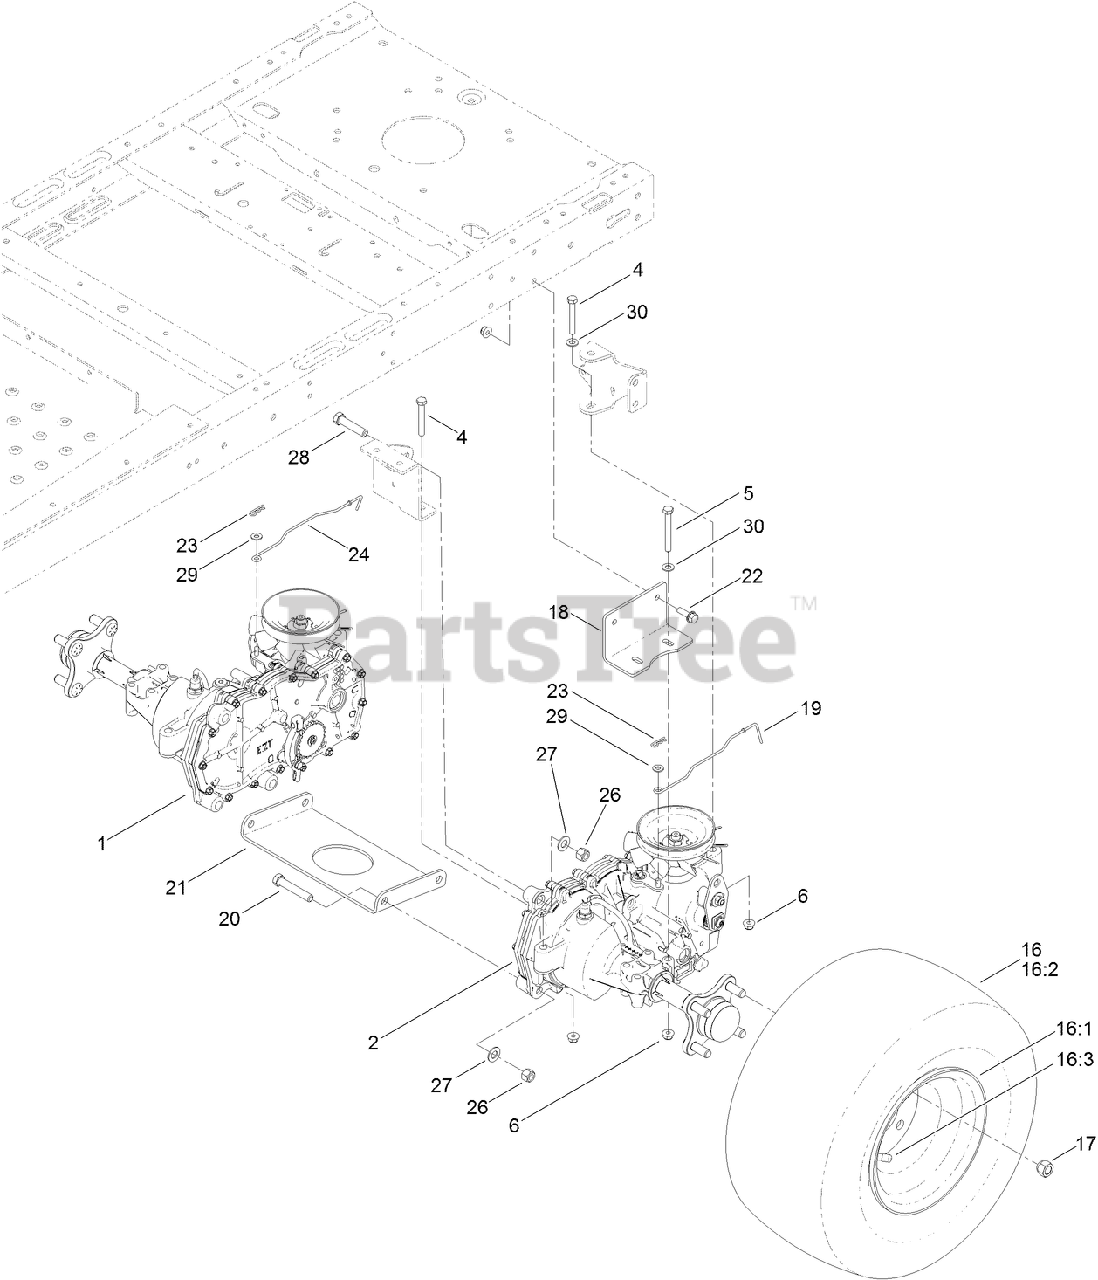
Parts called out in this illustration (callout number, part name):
1	RH HYDRO TRANSAXLE ASM
2	LH HYDRO TRANSAXLE ASM
4	SCREW-HH
5	SCREW-HH
6	NUT-HF, NI
16	4 PLY WHEEL AND TIRE ASM
16:2	TIRE-4 PLY
17	NUT-LUG
18	MOUNT-HYDRO
19	ROD-BYPASS, LH
20	SCREW-HH
21	PLATE-CROSS, HYDRO
22	SCREW-HHF
24	ROD-BYPASS, RH
26	NUT-LOCK, NI
27	WASHER-FLAT
28	SCREW-HH
29	WASHER-FLAT
30	WASHER-PLAIN
